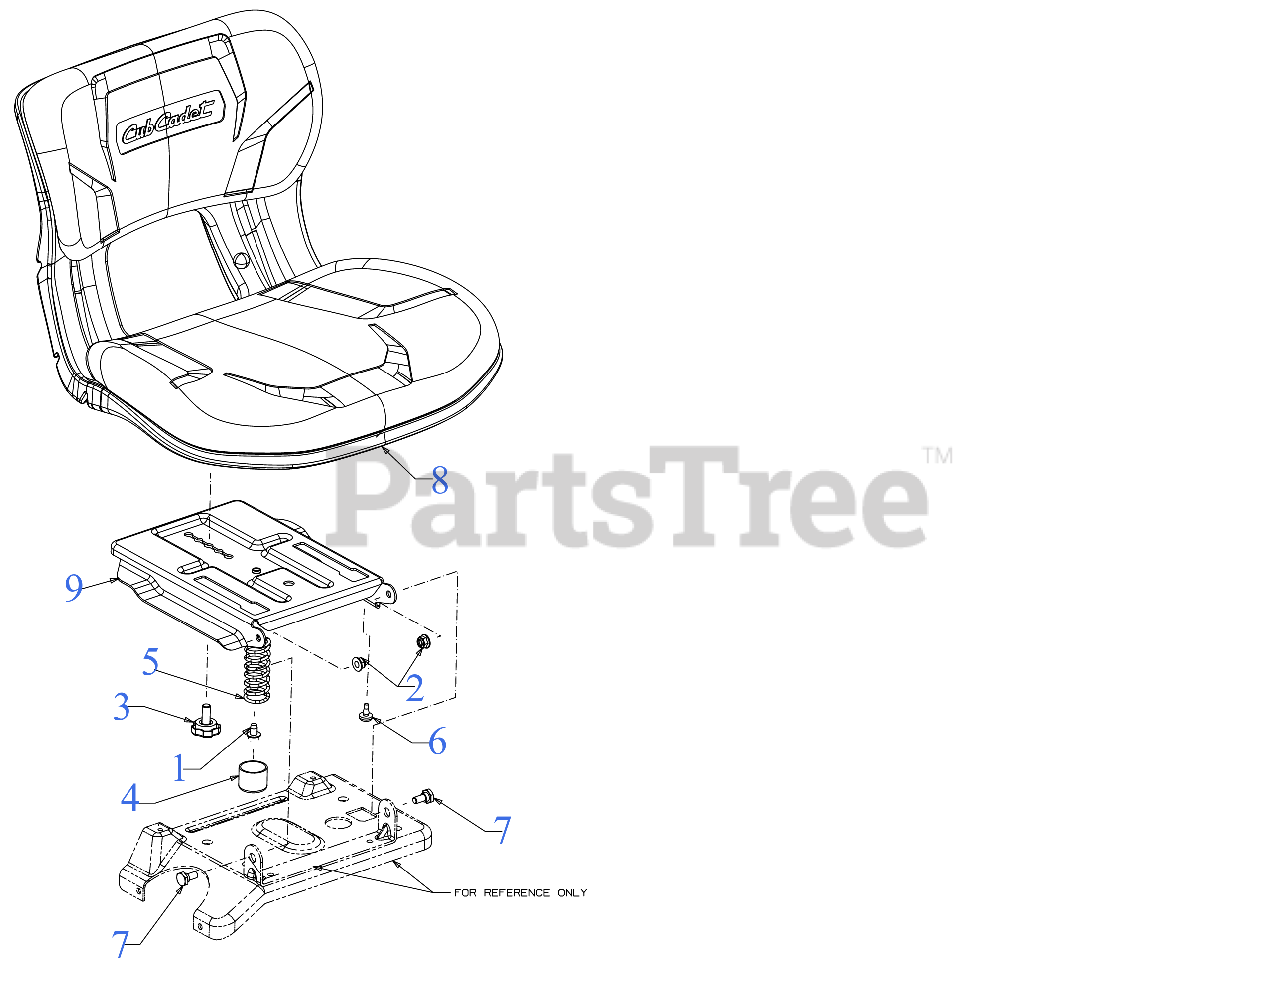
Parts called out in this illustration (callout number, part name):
1	SCREW 5/16-18 x .500
2	FLANGE LOCK NUT 5/16-18
3	SEAT ADJUSTMENT KNOB
4	SEAT SPRING CAP
5	SEAT SPRING
6	RUBBER BUMPER
7	SHOULDER SCREW .437 DIA x .180
8	HIGH SEAT (ARM OPT)
